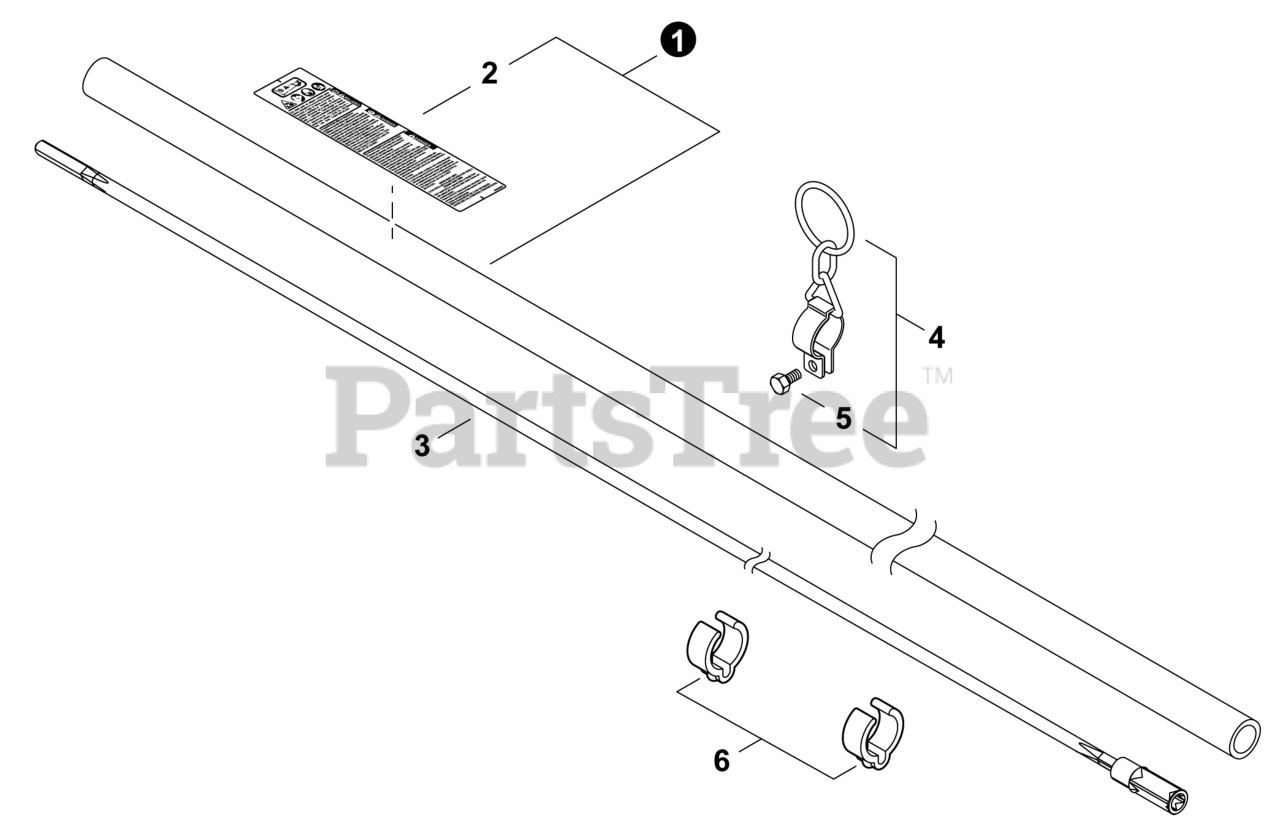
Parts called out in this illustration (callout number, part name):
1	MAIN PIPE ASSY
2	LABEL - CAUTION
3	DRIVESHAFT - FLEXIBLE
4	HANGER SET, HARNESS
5	BOLT, TORX 5x12
6	CLIP, CABLE 25 MM
